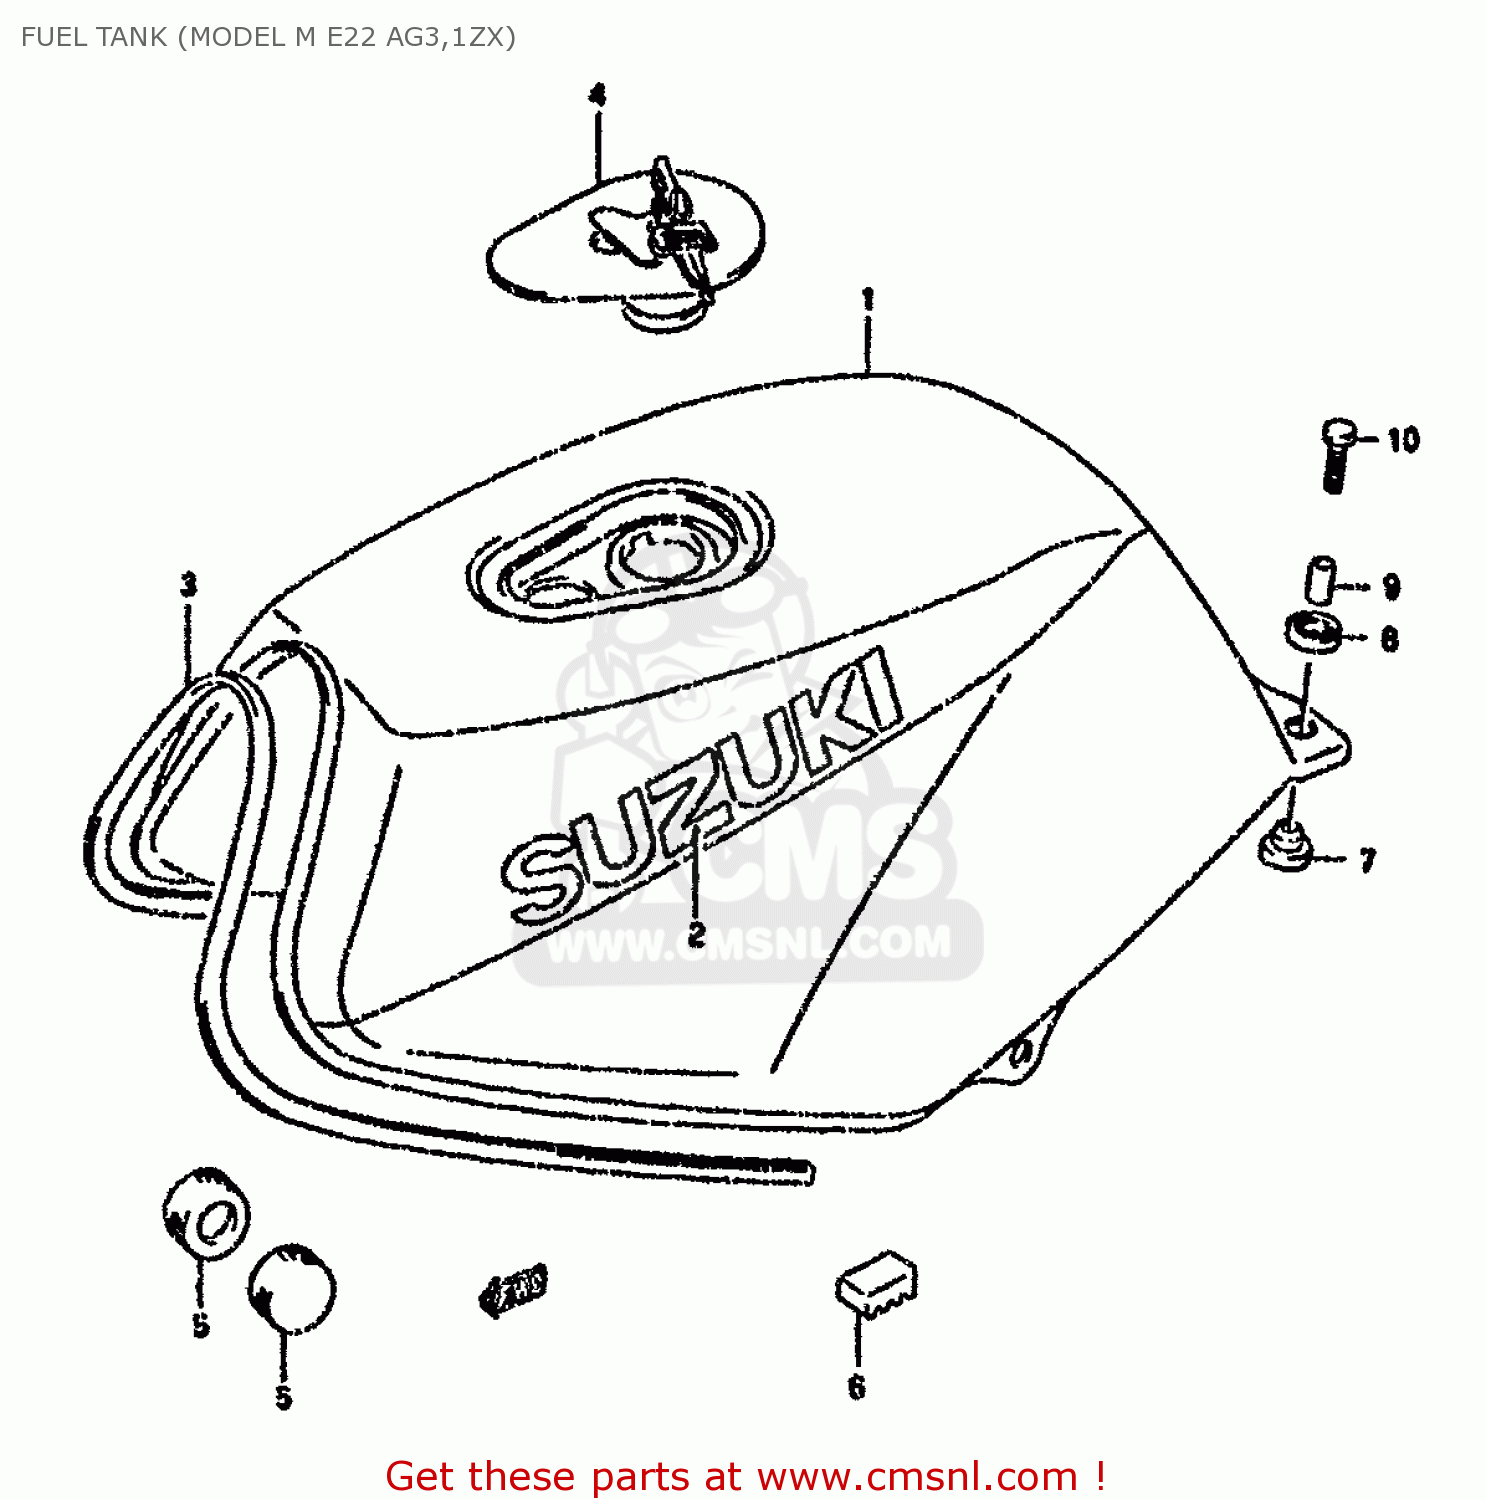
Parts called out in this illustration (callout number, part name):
1	TANK ASSY,FUEL (BLACK)
2	EMBLEM
3	MOLDING
4	CAP SET,FUEL TANK
5	CUSHION
6	CUSHION,FUEL TANK SIDE
7	CUSHION
8	CUSHION
9	CUSHION
10	BOLT
11	CUSHION
12	CUSHION
13	BOLT
14	WASHER (6.5X24X1.6)
15	BOLT
